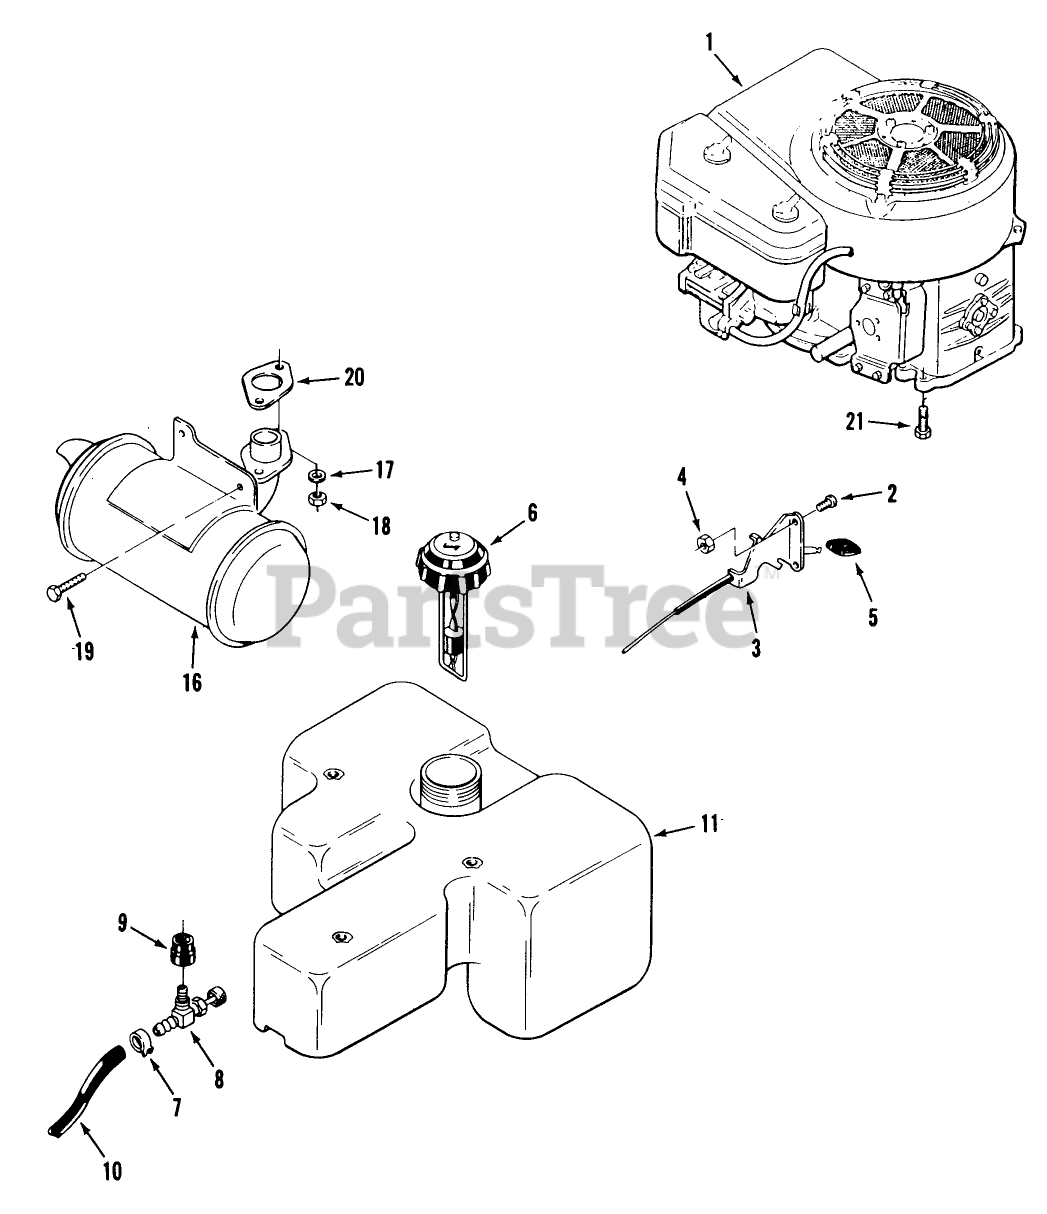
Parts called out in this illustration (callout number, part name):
1	Engine-17 HP-Kawasaki Model FC540 V K2800
2	Screw
3	THROTTLE-CONTROL
4	Nut
5	KNOB-THROTTLE
6	ASS'Y-GAUGE CAP
7	Clamp
8	VALVE-FUEL
9	BUSHING
10	Line-Fuel 53"
11	Fuel Tank
16	MUFFLER-EUROPE FC540
17	Lockwasher
18	Nut M8x1.25 257-H
19	Screw
20	OBS GASKET-EXH FC-540V
21	BOLT M8X1.25X35MM
